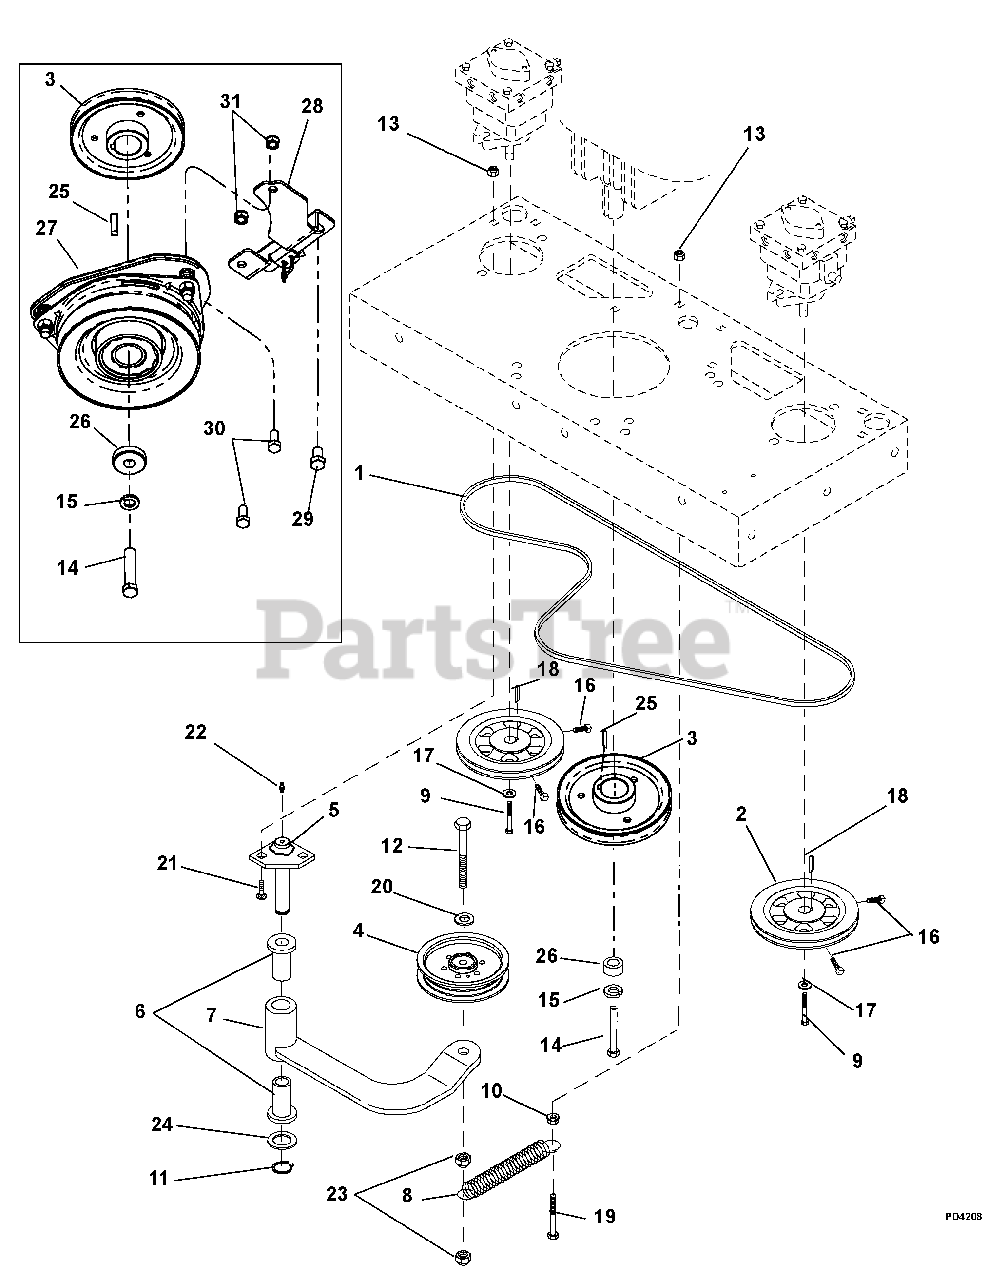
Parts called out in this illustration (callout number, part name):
1	Belt, Drive, Pump
2	Assembly, Pump Pulley w/ Set Screw
3	Sheave, Engine 4.75 x 1.125
4	Assembly, Idler 4
5	Weldment, Pivot Idler Mount
6	Bushing
7	Arm, Idler Weldment
8	Spring, External
9	Bolt, Hex M6 x 1.00 x 10
10	Locknut, M10 x 1.50
11	Ring, Snap, External .750 x .042 Ext
12	Bolt, Hex .38-16 x 2.50
13	Nut, Locking, Nylon M10-1.5
14	Bolt, Hex .44-20 x 2.25 Grade 5 EP80
15	Washer, Locking .44 x .109
16	Set Screw
17	Washer, Flat .250 Wide Heavy
18	Key, M5 x M5 x M30 RD
19	Cap Screw, Spring Anchor, M10
20	Washer, Flat .406 x .812 x .065
21	Carriage Bolt, M10 x 1.5 x 25
22	Lubrication Fitting
23	Nut, Locking, Nylon .38-16
24	Bushing, 3/4 Machine
25	Key, .250 x .250 x .995 Taper
27	Clutch, Ogura GT1A-AR03
28	Plate, Clutch Dog
29	Bolt, Hex M6 x 1.0 x 10
30	Bolt, Hex .31-18 x .75 Grade 5
31	Nut, Locking, Nylon .312-18
